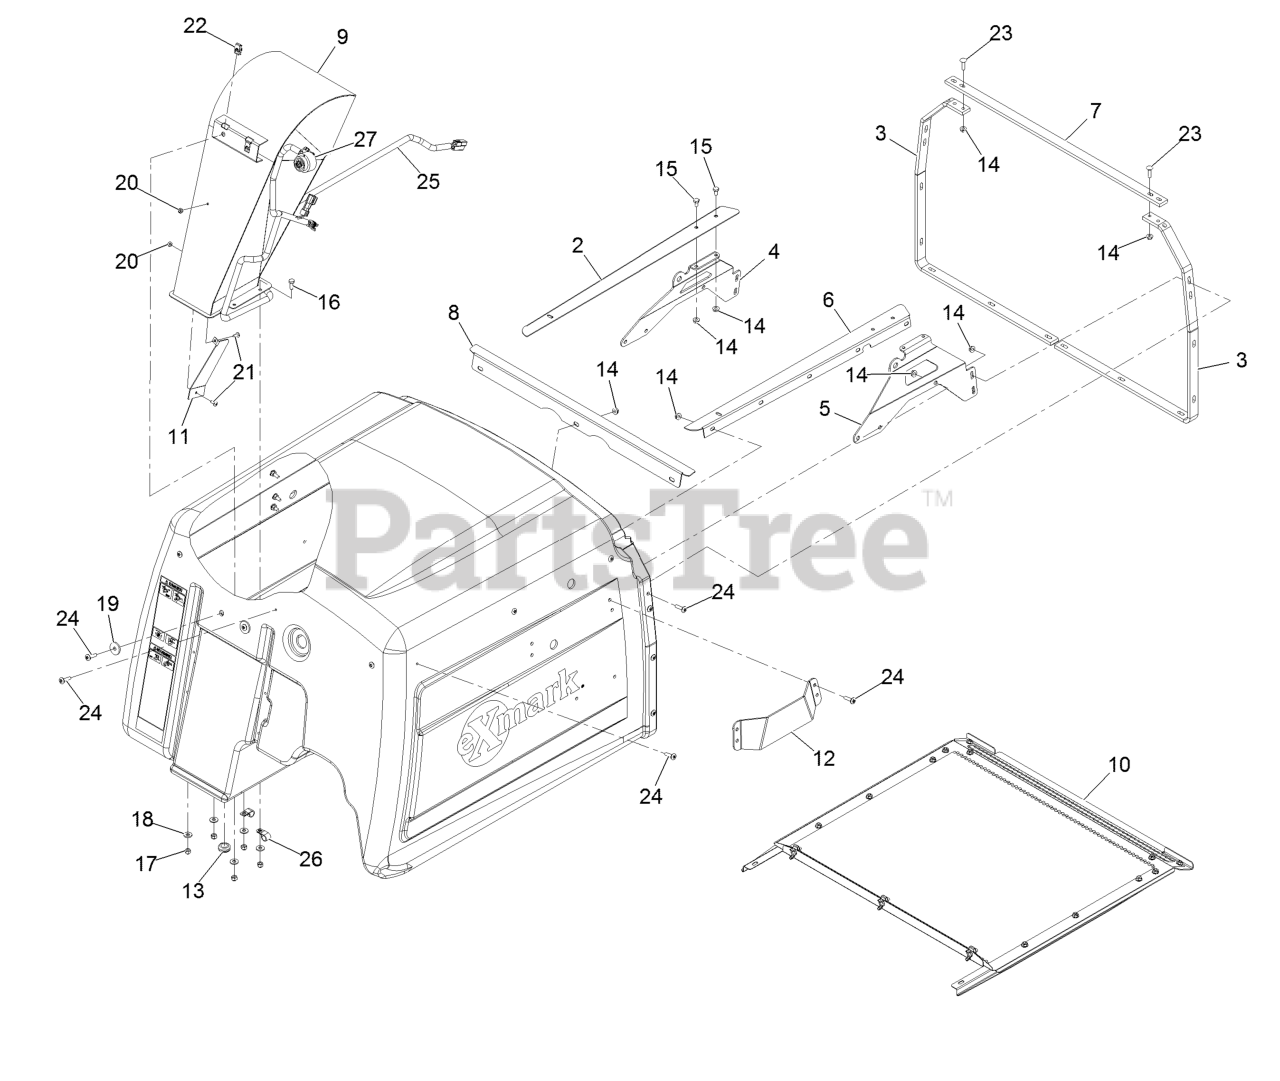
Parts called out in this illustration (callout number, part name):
2	Angle-Screen Track, RH
3	Reinforcement-Hopper
4	Brace-Door Pivot, RH
5	Brace-Door Pivot, LH
6	Angle-Screen Track, LH
7	Bracket-Frame Connect
8	Channel-Screen, Front
10	Hopper Screen ASM
11	Deflector-Discharge Chute
12	Plate-Guard
13	Grommet
14	Nut-Whizlock 1/4-20
15	Screw-HH 1/4-20 X 1/2
16	Screw-HH 1/4-20 X 3/4
17	Nut-Nyloc 1/4-20
18	Washer-1/4 Std
20	Nut-Nyloc #10-24
21	Screw-Truss HD #10-24 X 1/2
22	Nut-Retainer-Panel 1/4-20
23	Bolt-Carriage 1/4-20 X 1
24	Screw-Truss HD 1/4-20 X 1
25	Harness-Wire, Hopper
26	Clip-Loom 1/2
27	Alarm-Tone, Dual
